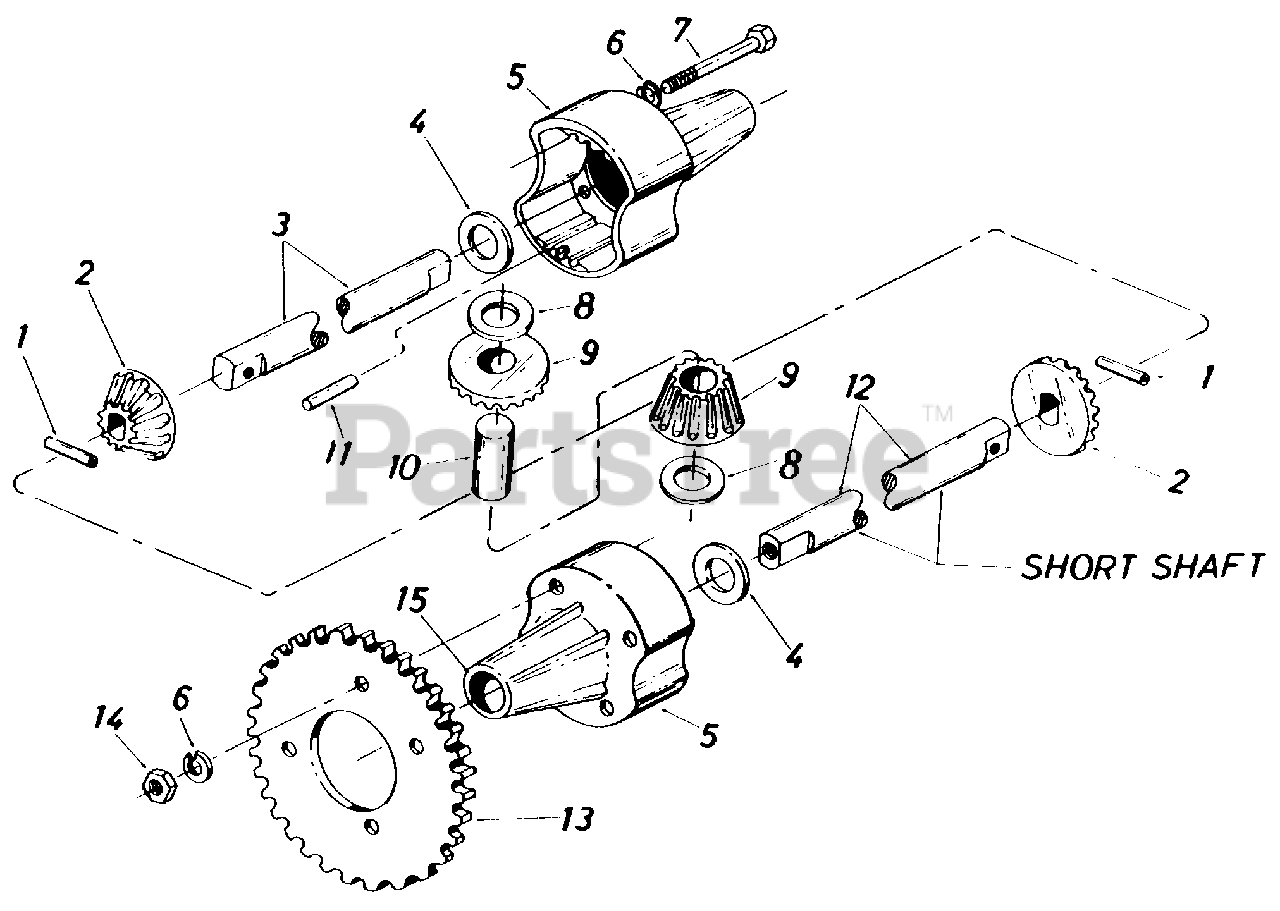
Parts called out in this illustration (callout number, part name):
1	Spring Pin Spiral 3116" Dia. x 1.00" Lg.
2	Gear-Double"D" Hole
3	Shaft (Long) -15.11" Lg.
4	Fl-Wash. .760 I.D. x 1.49 0. D.
5	Housing Half
6	L-Wash. 5/16" I.D.
7	Hex Bolt 5/16-24 x 4.00" Lg.
8	Fl-Wash. .640 I.D. x .24 O.D.
9	Gear-Round Hole
10	Drive Pin
11	Dowel Pin 3/16" Dia. x .62" Lg.
12	Shaft (Short) 7.58" Lg.
13	Sprocket-48 Teeth
14	Hex Cent. L-Nut 5116-24 Thd.
15	Flange Bearing
